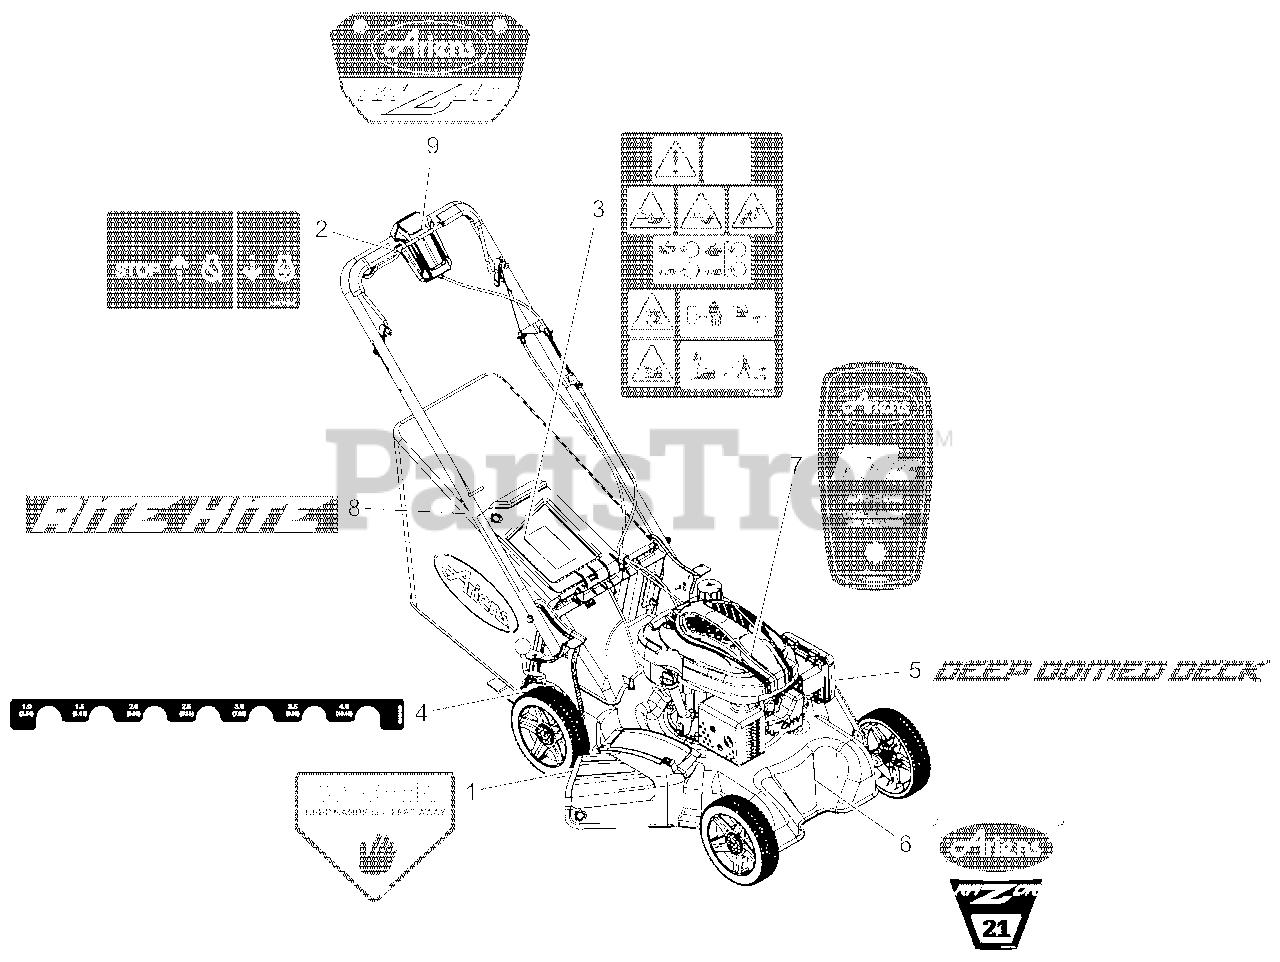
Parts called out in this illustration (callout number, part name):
1	DECAL, DANGER
2	DECAL - ENGINE CONTROL
3	DECAL,MAIN SAFETY_WAW LM
4	DECAL, HOC
5	DECAL, DEEP DOME DECK
6	DECAL, ARIENS RAZOR STYLE
7	DECAL, ENGINE STYLE - ARIENS
8	DECAL, RITE HITE
9	DECAL, ARIENS RAZOR - SMALL
